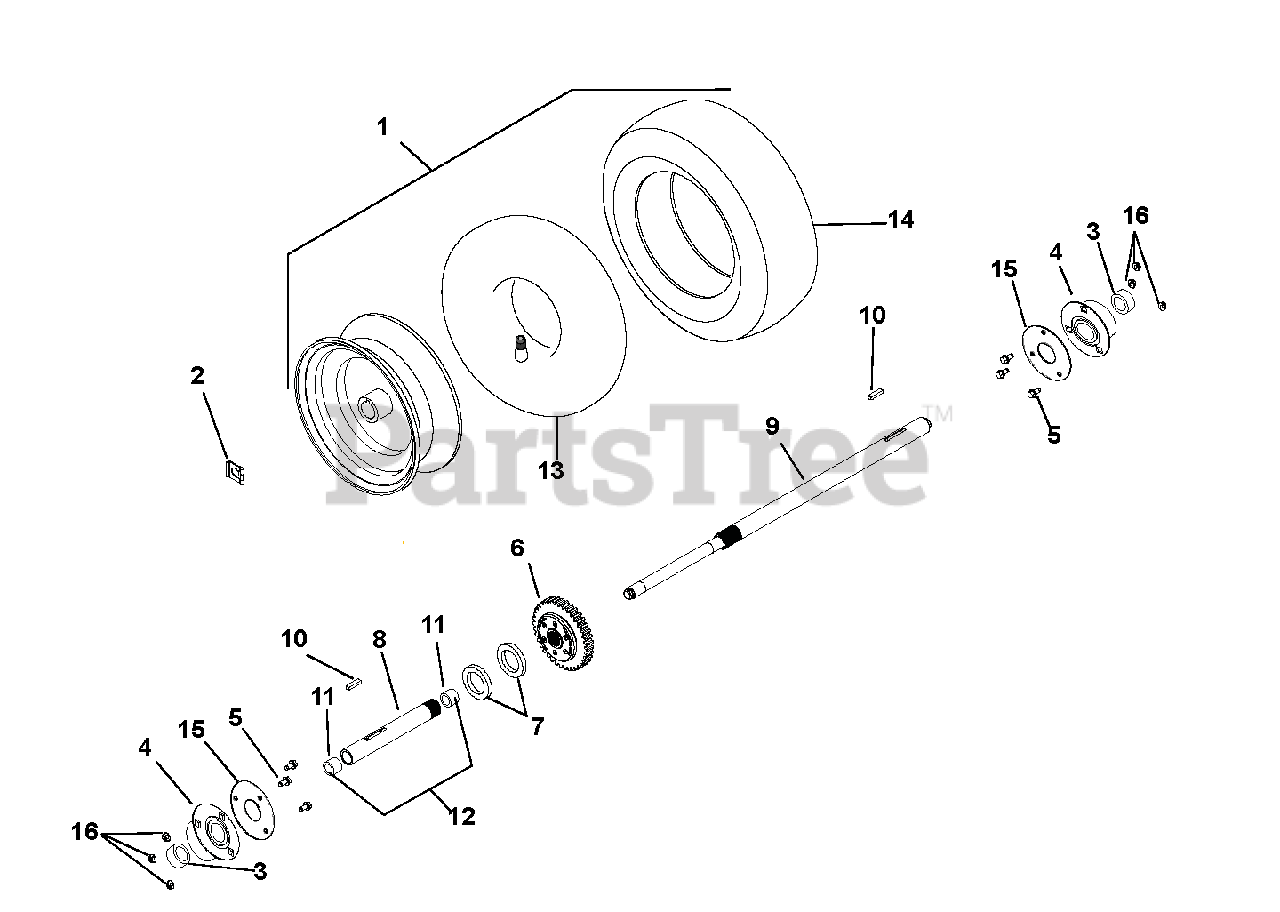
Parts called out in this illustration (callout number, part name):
1	TIRE/WHEEL, RH 16X6.50-8 DIFF
2	CLIP, SNAP .625 DIA
3	SPACER, PRO AXLE BEARING
4	BRG-FLG 1.003/1.000 3 BOLT
5	@BLT-HEX .25-20X.75 GR5 YWZC
6	DIFFERENTIAL, AUTOMATIC
7	WSHR-FL-STL- 1.062X2.0X.134 YZ
8	AXLE, SHORT-PRO AUTO DIFF
9	AXLE, LONG-PRO AUTO DIFF
10	KEY-RECT .25X.188X1.00
11	BSHG-SLV .706X.764X.75 BRZ
12	AXLE, SHORT-AUTO W/BUSHINGS
14	TIRE, 16X6.50-8 K478
15	PLATE, BEARING SPACER
16	@NUT-LK-TOP-FLG .25-20 YWZC
